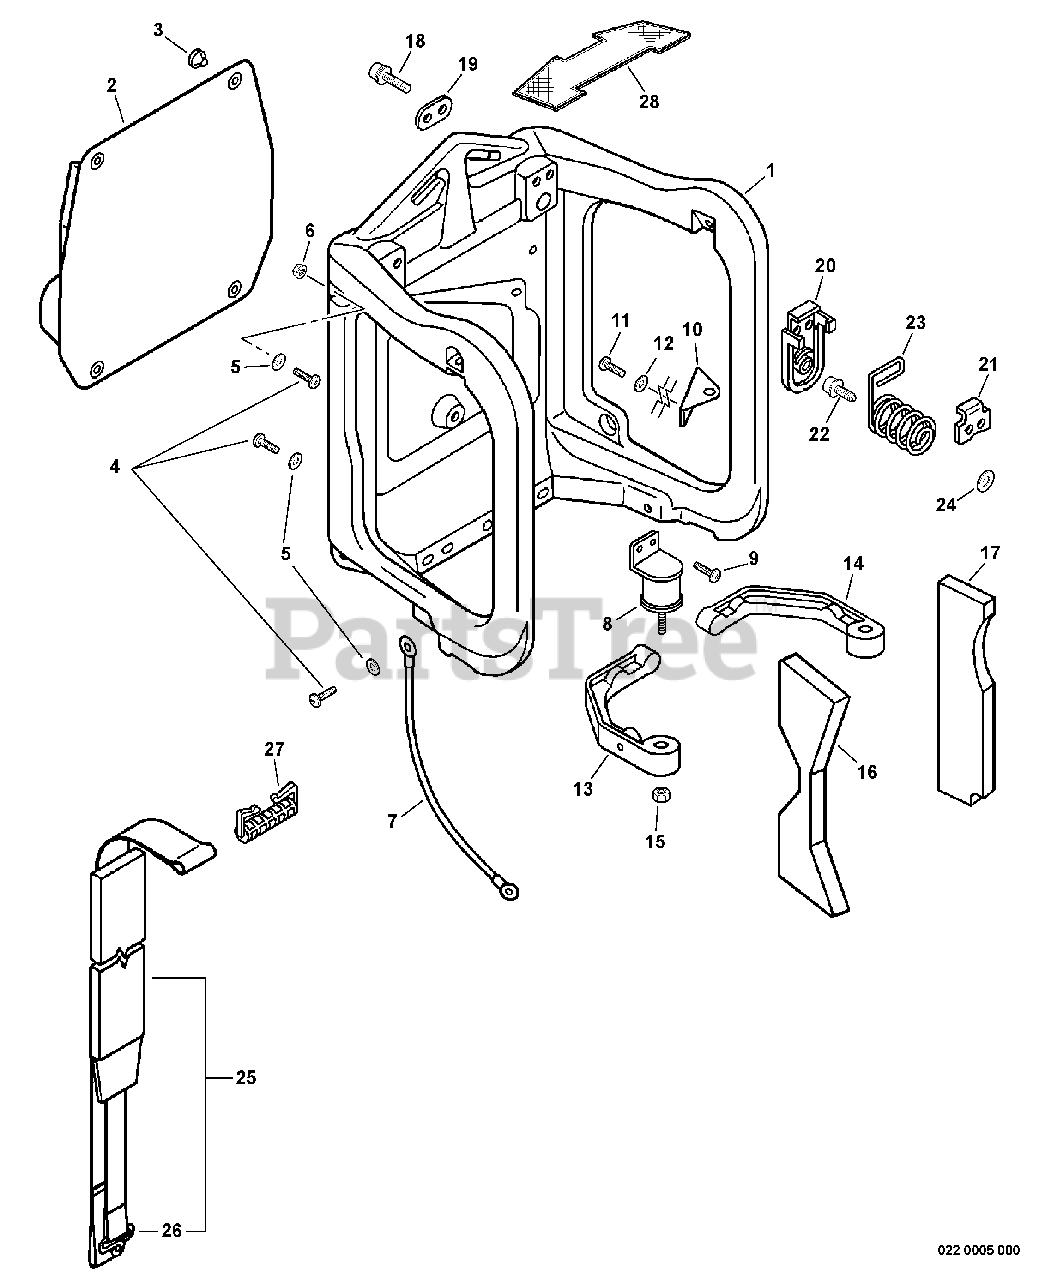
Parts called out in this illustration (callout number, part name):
1	FRAME, BACKPACK
2	CUSHION, BACKPACK
4	SCREW 5×16
5	WASHER 5.5×18×1
6	NUT, FLANGE M5
7	LEAD - GROUND
8	CUSHION
9	SCREW TAPPING 5×16
10	BRACKET, HANGER
11	SCREW 5×14
12	WASHER 5.5×18×1
13	CONNECTOR, FRAME - LEFT
14	CONNECTOR, FRAME - RIGHT
15	NUT, FLANGE M5
16	PAD, FOAM - LEFT
17	PAD, FOAM - RIGHT
18	BOLT 5×20
19	PLATE, EYE
20	HOLDER, SPRING
21	PLATE, THREADED
22	BOLT 5×20
23	SPRING, COMPRESSION
24	WASHER 5.5×16×2T
25	HARNESS ASSY, BACKPACK
26	RING, HARNESS
27	CLIP, HARNESS
28	COVER, DUST
